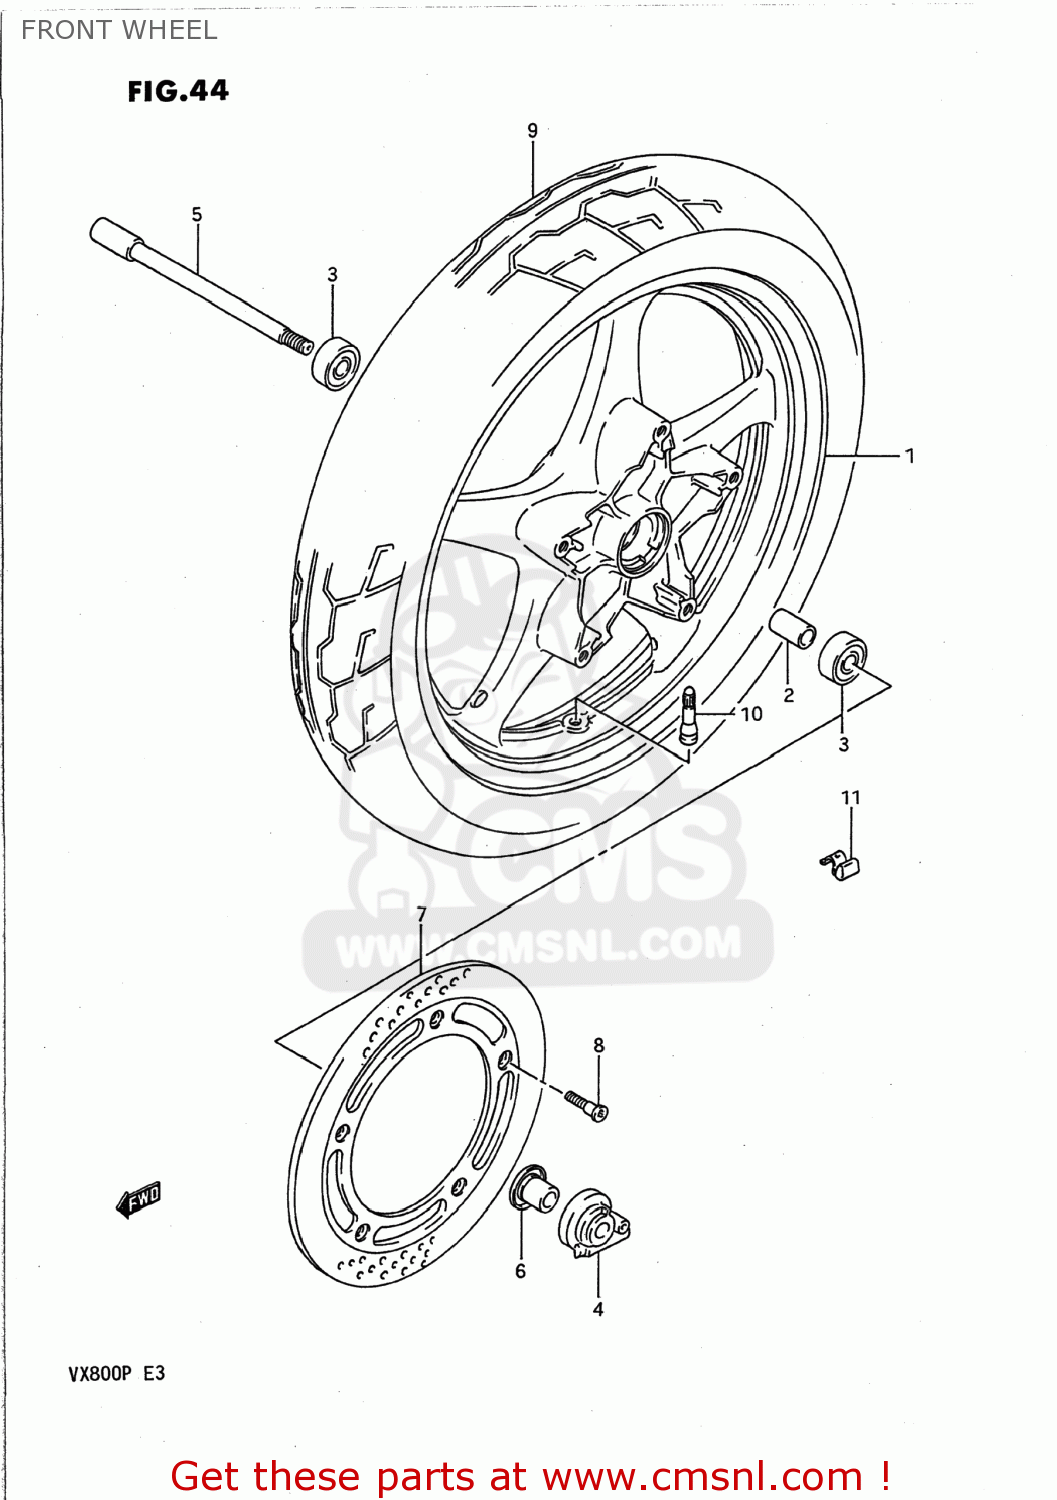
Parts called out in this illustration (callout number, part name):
1	WHEEL,FRONT
2	SPACER(15.3X21.7X63)
3	BEARING
4	BOX ASSEMBLY,SPEEDOMETER GEAR
5	AXLE,FRONT
6	SPACER,FR HUB BEARING,R
7	DISC,FR BRAKE,L
8	BOLT 8X33
9	TIRE 110/80-18 58M,MET
10	VALVE ASSY,WHEEL RIM(TR412)
11	BALANCER,WHEEL
